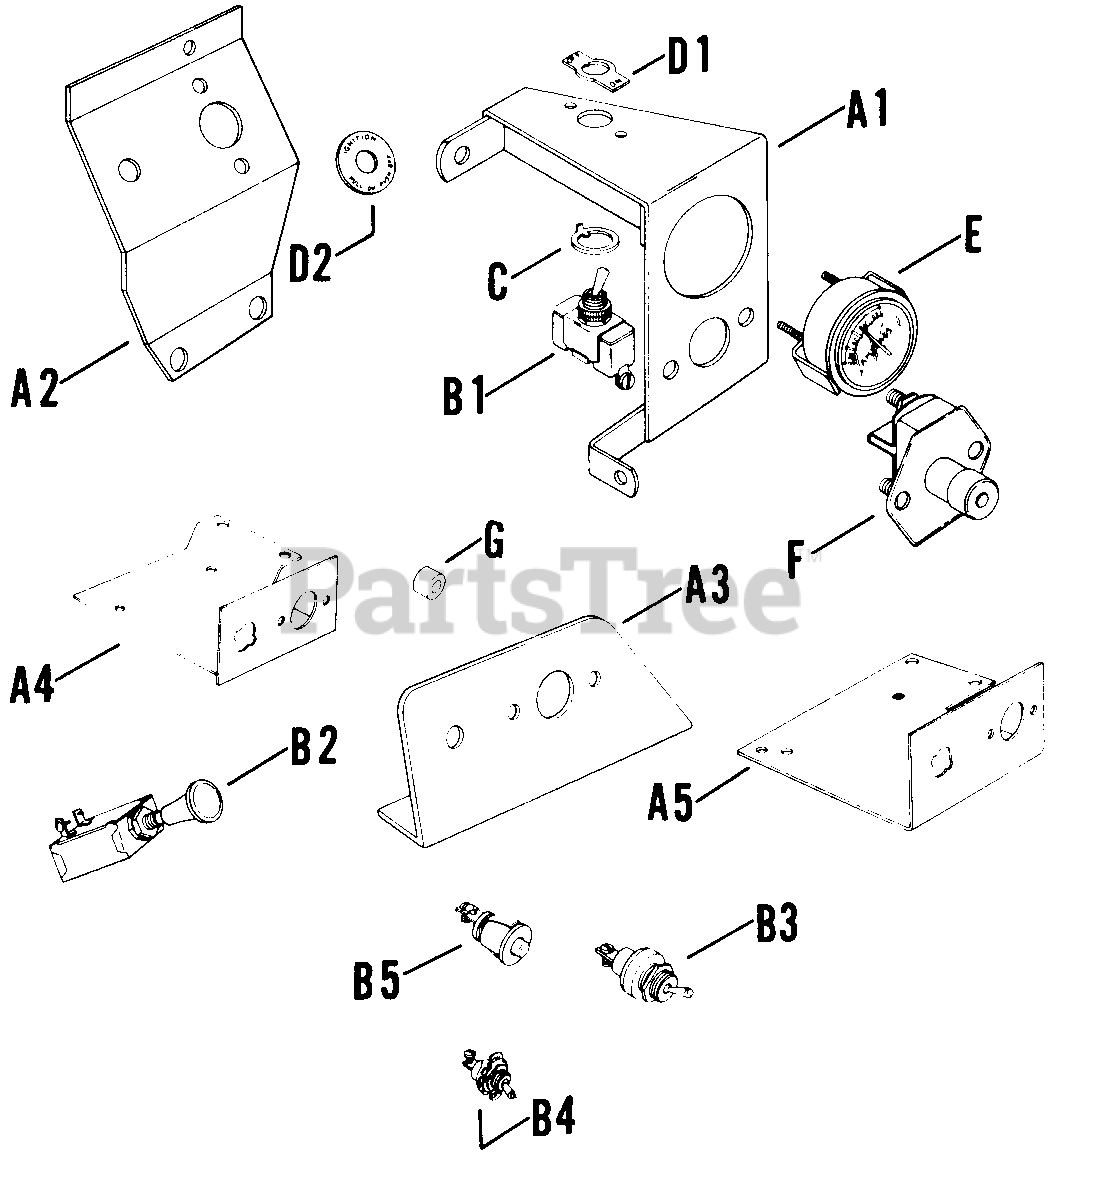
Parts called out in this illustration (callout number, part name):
B2	SWITCH - DISCONTINUED
D2	PLATE - DISCONTINUED
F	SWITCH - USE 237851
